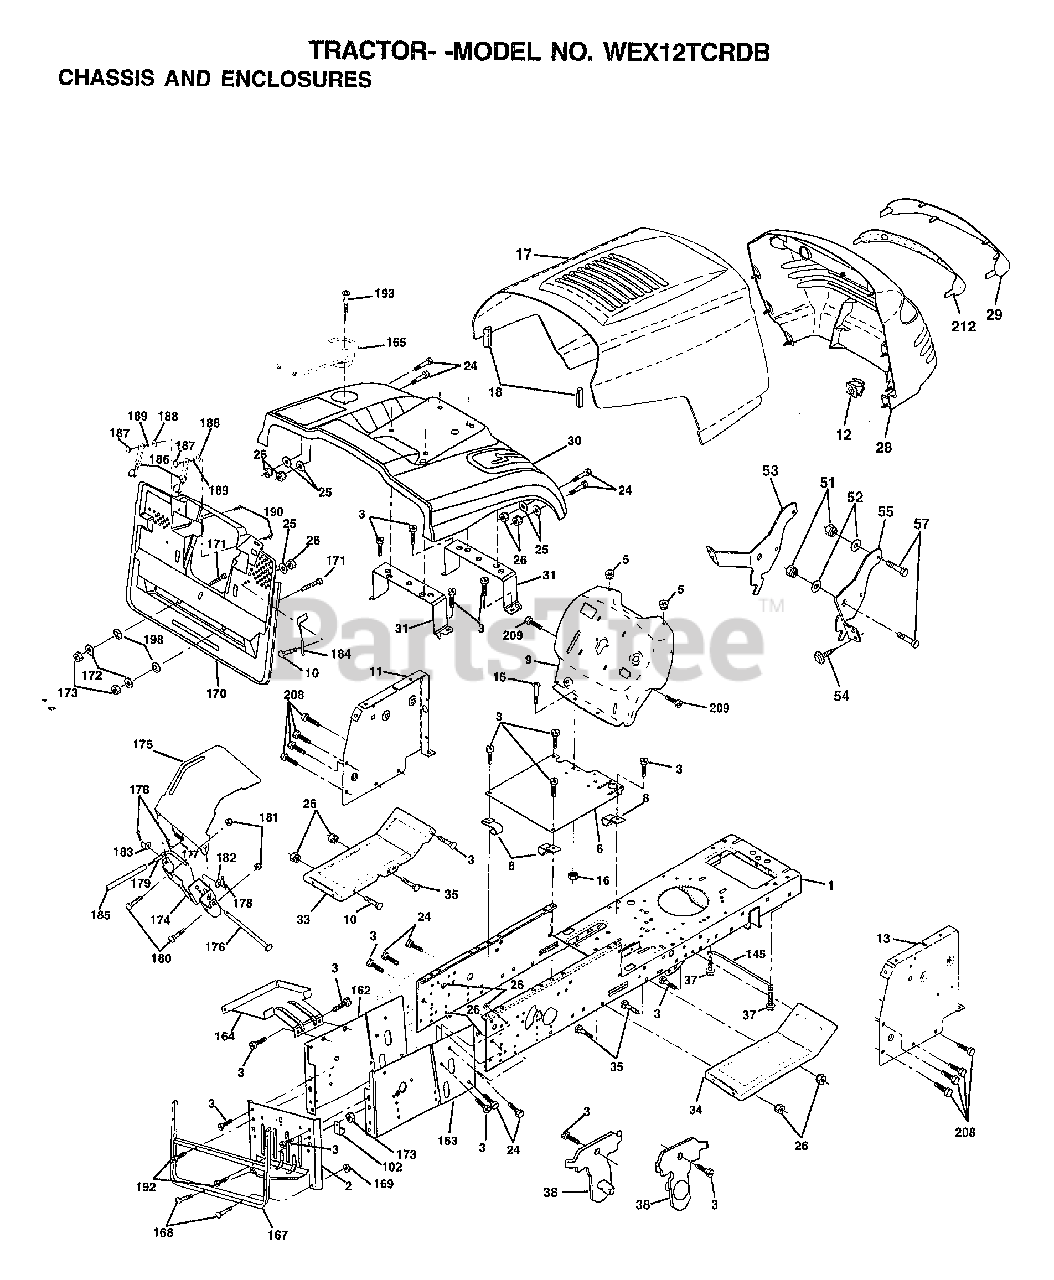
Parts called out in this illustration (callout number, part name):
2	DRAWBAR.CRD
3	SCREW
5	BUMPER-HOOD/DASH
6	SADDLE
8	"CLIP,INSULATOR"
9	DASH
11	"PANEL-DASH,LH"
12	CLIP.TINNERMAN
15	SCREW
17	HOOD.STEEL.ASSY
24	BOLT
25	WASHER
26	NUT
28	GRILLE
29	LENS.GRILLE
30	FENDER.GEAR.CRD.GREEN
31	BRKT.SUPT.FENDER.CRD
33	FOOTREST.LH.LT/GT
34	FOOTREST.RH.LT/GT
35	BOLT
37	SCREW LT
38	BRKT ASM PIVOT MOWER REAR
51	NUT
52	WASHER
53	BRACKET.GRILLE.LH
54	SCREW.HEX.WS.HD
55	BRACKET.GRILLE.RH
102	CLIP T
145	"ROD POVOT,CHASSIS"
162	BRKT.EXT.CHASSIS.LH.CRD
163	BRKT.EXT.CHASSIS.RH.CRD
164	SUPPORT.BATTERY.CRD
165	COVER.BATTERY.CRD.BLACK.LT
167	SUPT.ASM.BACKPLATE
168	BOLT-RD HD SQ NK
170	COVER.BACKPLATE.BLACK
171	BOLT.HEX.3/8-16X2-1/2
173	NUT
174	BRKT.SWITCH.FBI.CRD
175	GRUARD.DOOR.REAR.CRD
176	HINGE PIN
177	SPRING.COVER.LH
179	ROD.PIVOT.FBI.CRD
182	WASHER.385X.625
183	WASHER
184	BRKT.ACTUATOR.BAG.CRD
185	TUBE.LEVER.SWCH.FBI.CRD
186	LATCH ASSY.BAGGER
187	WELDNUT
188	WASHER #10
189	LOCKWASHER
190	SCREW
192	SCREW LT
193	SCREW
198	NUT PUSH
208	SCREW
209	SCREW
212	INSERT LENS REFLECT
